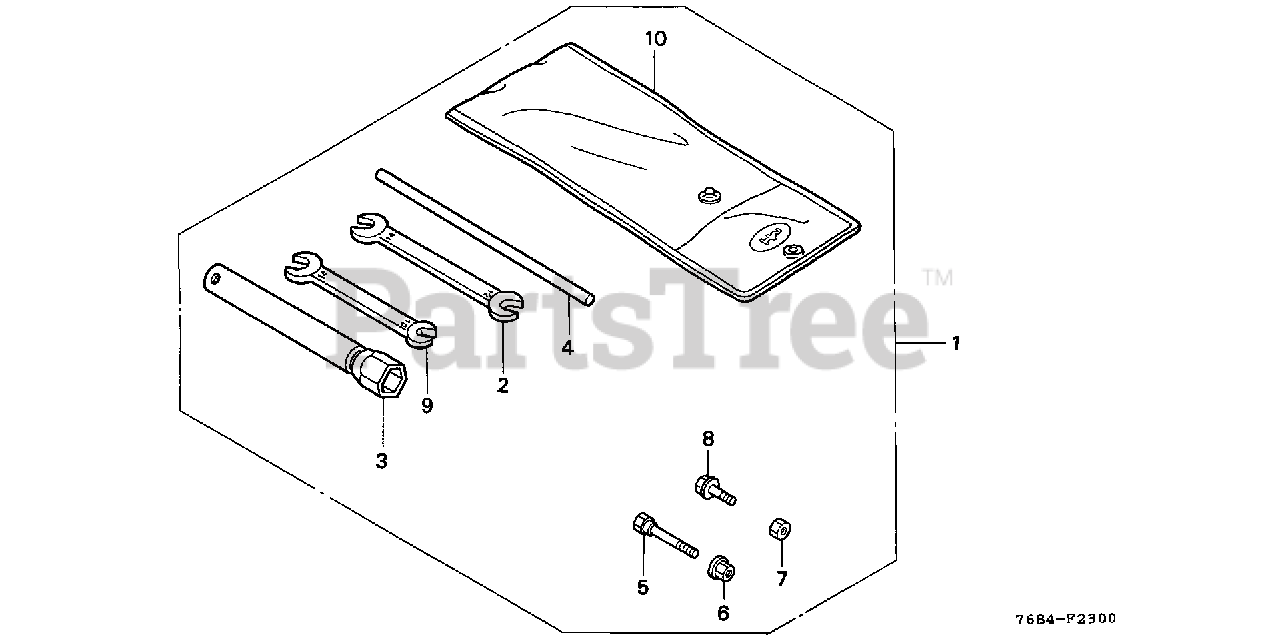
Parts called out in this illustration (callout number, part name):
1	TOOL KIT (NOT AVAILABLE)
2	SPANNER (12X14)
3	WRENCH, SPARK PLUG
4	HANDLE, BOX WRENCH
5	BOLT, LOCK
6	NUT, SELF-LOCK (6MM)
8	BOLT, HEX. (6X16)
9	SPANNER (10X14)
